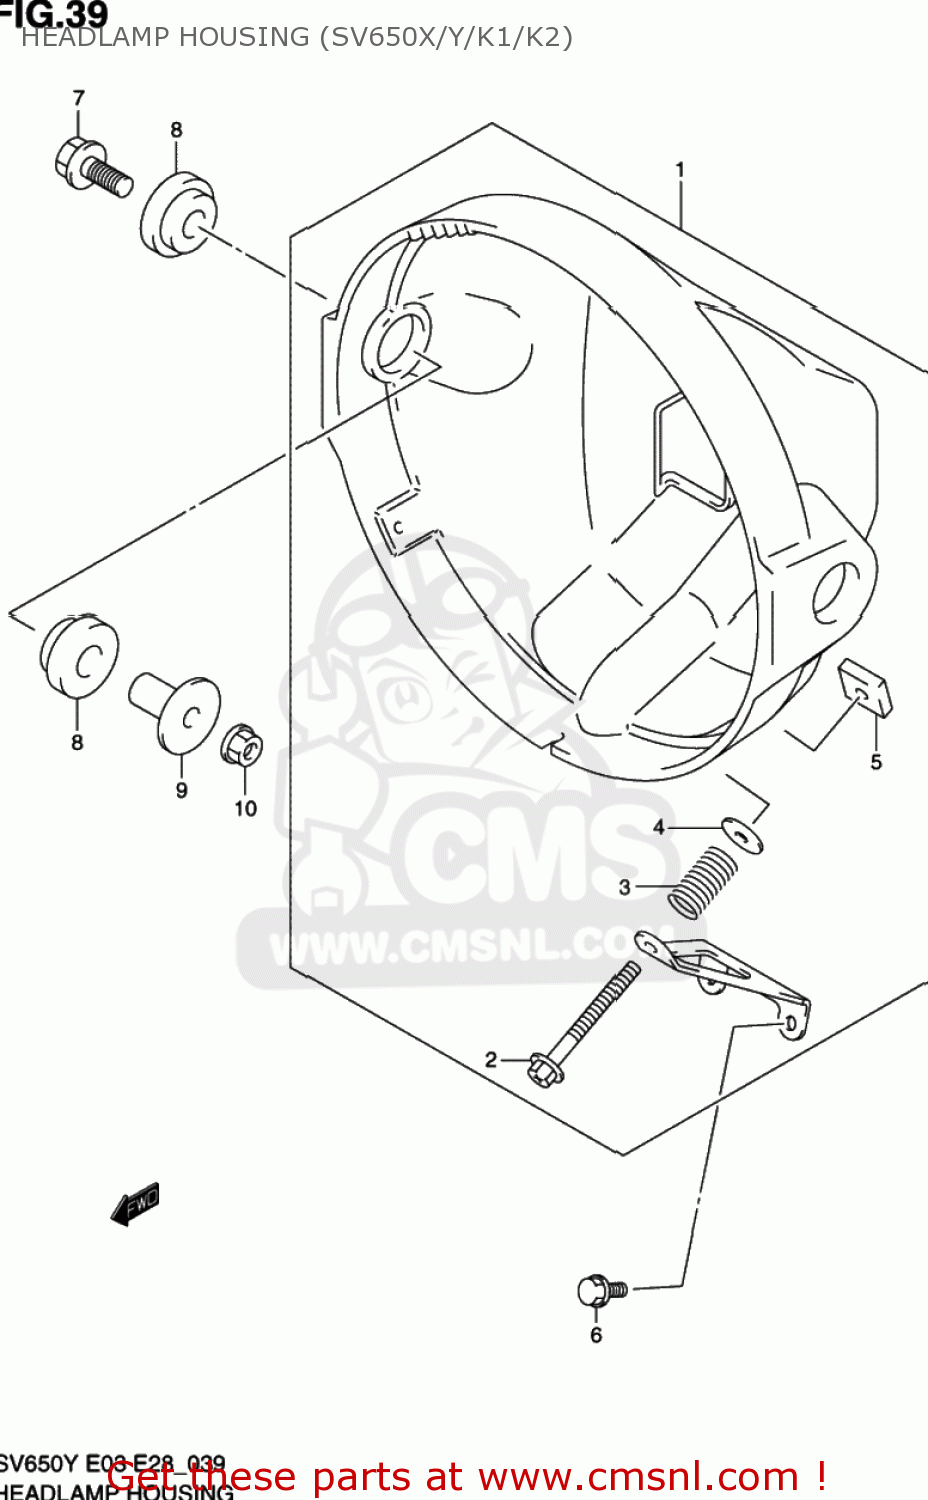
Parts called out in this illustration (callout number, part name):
1	HOUSING ASSY,HEADLAMP
2	BOLT,HEADLAMP ADJUSTER
3	SPRING,HEADLAMP ADJUSTER
4	WASHER
5	NUT,HEADLAMP ADJUSTER
6	BOLT
7	BOLT
8	CUSHION
9	SPACER(8.6X12X20)
10	NUT
